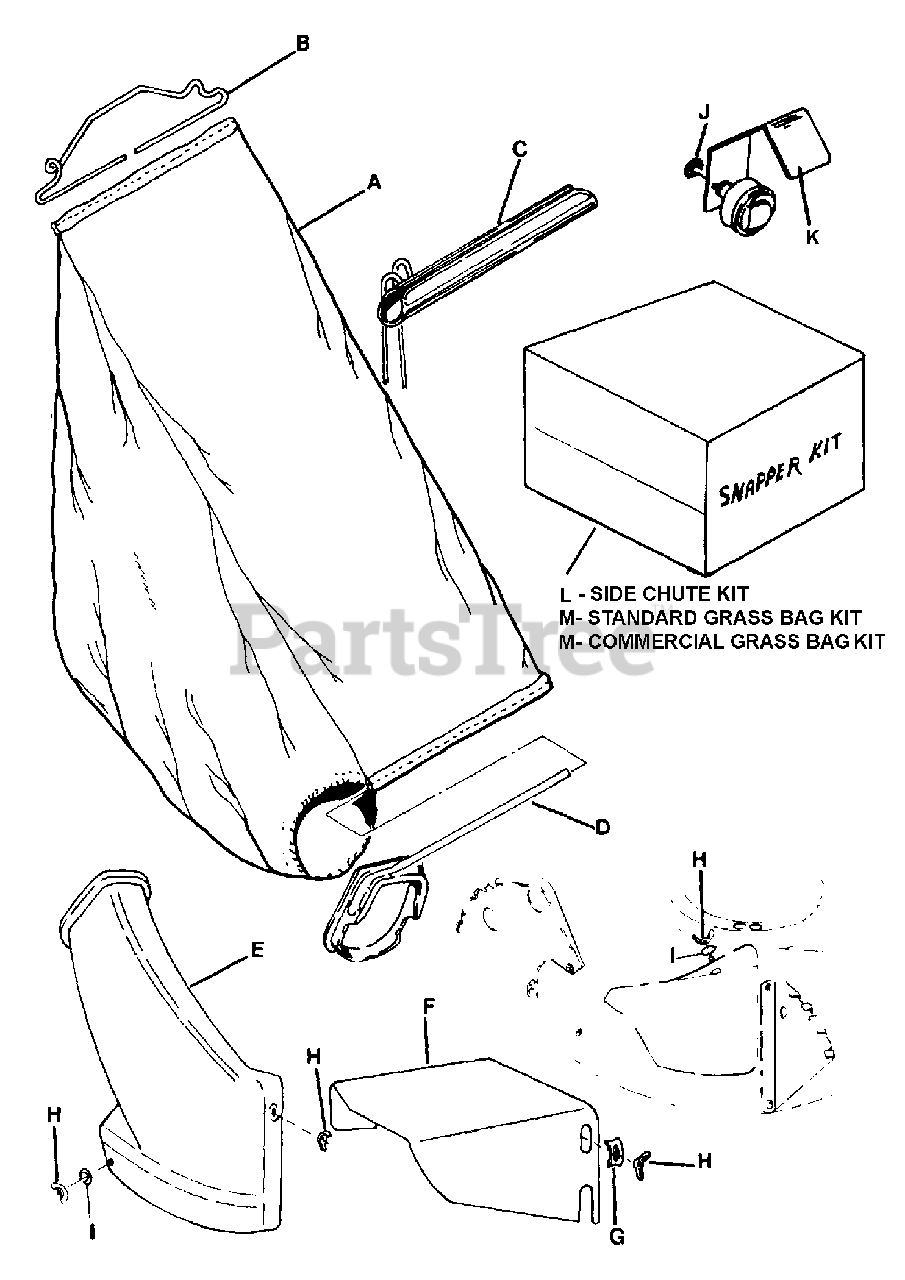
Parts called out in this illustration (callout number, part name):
A	GRASS BAG, STANDARD 21" (26.875x10.75)
A	GRASS BAG, COMMERCIAL 21" (29.25x10.75)
B	WIRE, BAG CONNECTOR REAR
C	SLIDER, BAG CLOSURE
D	CONNECTOR, GRASS BAG
E	ADAPTER, GRASS BAG DECK
F	SIDE CHUTE (plastic) (Metal version shown)
G	CLAMP (Used with Side Chute only)
H	WLN, 5/16C YZ
I	WASHER, 5/16 SAE
J	LOCKWASHER, 13/16" INTERNAL TOOTH
K	SHIELD, EXHAUST HEAT
